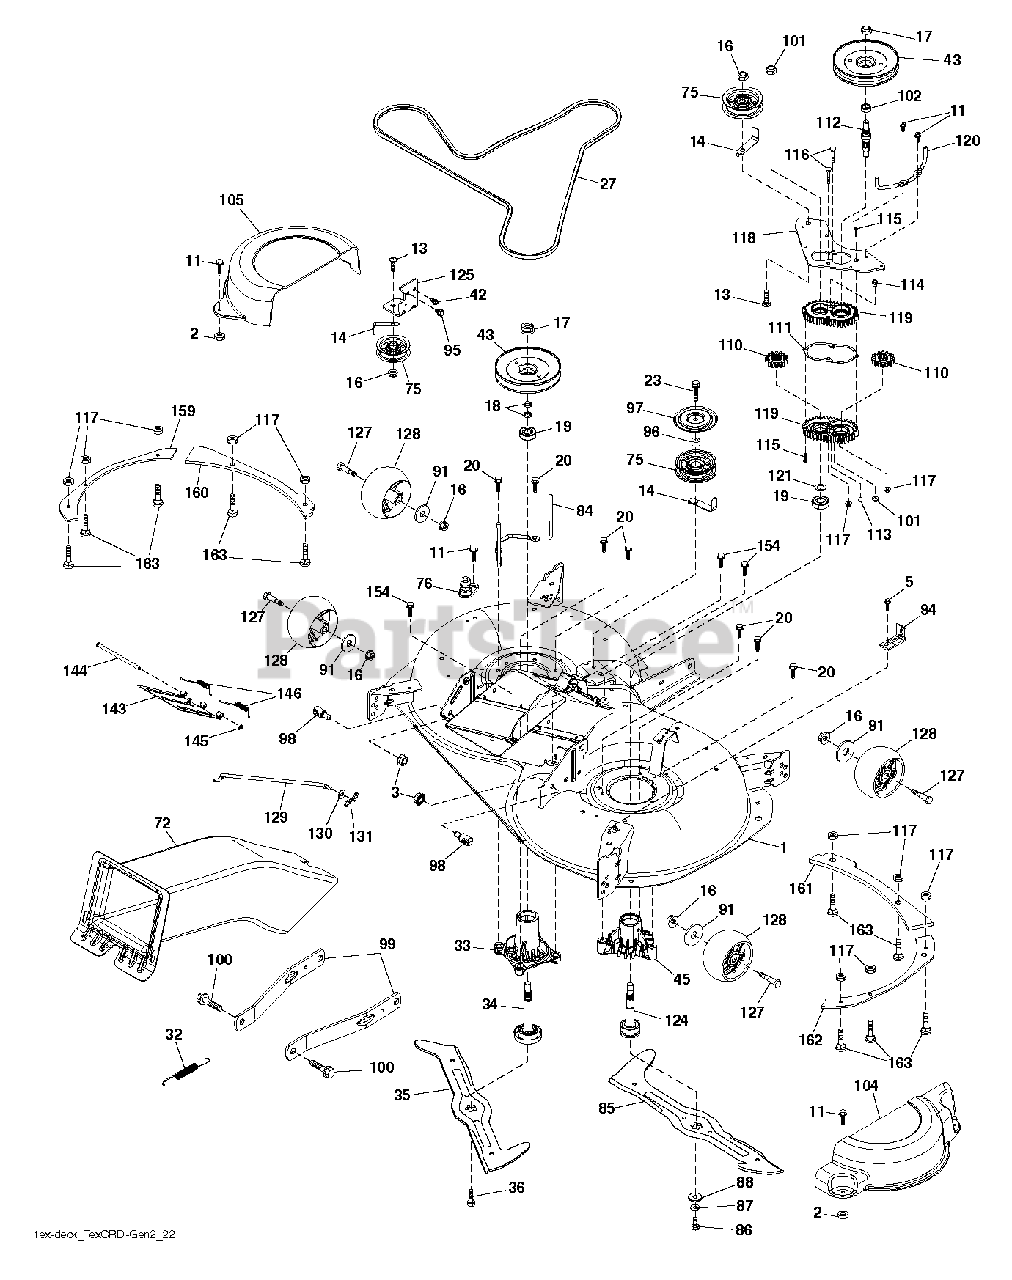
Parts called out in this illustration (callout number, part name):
1	DECK SVC 107HP.EZMUL.498
2	PALNUT 1/4
3	NUT LOCK HEX FLANGE 5/16-18
5	BOLT.5/16HEX.WHS.HD
11	SCREW.1/4-20X5/8
13	BOLT.3/8-16X1.50
14	KEEPER, BELT IDLER
16	NUT LOCK FLG 3/8-16 UNC
17	NUT.FLANGE.LOCK.TOP
18	WASHER.SPACER.MANDREL
20	SCREW, WASHER HEAD
23	SCREW LT
27	BELT BELT. ELECTRIC MOWER DRIV
32	SPRING 107CM & 97CM ELECTRIC D
33	HOUSING.MANDREL.REV.TALL.N/GRS
34	SHAFT ASM.REV.TALL.N/GREASEBL
35	BLADE.107.LH.SINGLE.NON.QD
36	BOLT.WASHER.ASM.7/16-2
42	SCREW
43	PULLEY PULLEY MANDREL 5.438 PD
45	RP HOUSING.MANDREL.REV.REVS.
72	CHUTE.107/97.TEX.GEN2.TRIMMED
75	FLAT IDLER PULLEY
76	PORT.WASHOUT
84	KEEPER KEEPER. LH MANDREL BELT
85	BLADE.107.RH.SINGLE.NON.QD
87	LOCKWASHER
88	WASHER.BLADE
91	WASHER
94	BRKT.CLUTCH.CABLE
95	SCREW, 3/8-16X3/4
96	SPACER
97	PROTECTOR
98	STUD.FASTNER.W/ANTI-ROTATE
99	ARM.SUSPENSION.MOWER.R
100	BOLT.SHOULDER
101	NUT.CROWNLOCK.9/16 -18.UNC
102	SPACER BEARING
110	GEAR GEAR OUTPUT
111	GASKET GASKET GEARCASE
112	SHAFT SHAFT. CRD GEARCASE ADAP
113	PLUG PLUG OIL
114	VALVE VALVE RELIEF
115	SCREW
116	BOLT.CARIGE.SS.1/4-20X1.75GR5
117	NUT T
118	ARM ARM. CLUTCHING 107 TEX CRD
119	GEARCASE GEARCASE SUBASM
120	KEEPER KEEPER. RH MANDREL BELT
121	WASHER WASHER
124	SUB.ASM.REVERSE.THREAD.REV
125	BRACKET
127	BOLT.SHOULDER.3/8-16X3-5/8.
128	WHEEL. GUAGE RALLY
129	ROD ROD. SWAY CRD GEN II
130	WASHER
131	PIN.COTTER.5/16.BOW TI
143	COVER DOOR.107 CM CRD EZ MULCH
144	PIN PIN.HINGE
145	E-RING.5/16"
146	SPRING SPRING: EZ MULCH DOOR
154	SCREW T-30 1/4-20 X
163	BOLT
